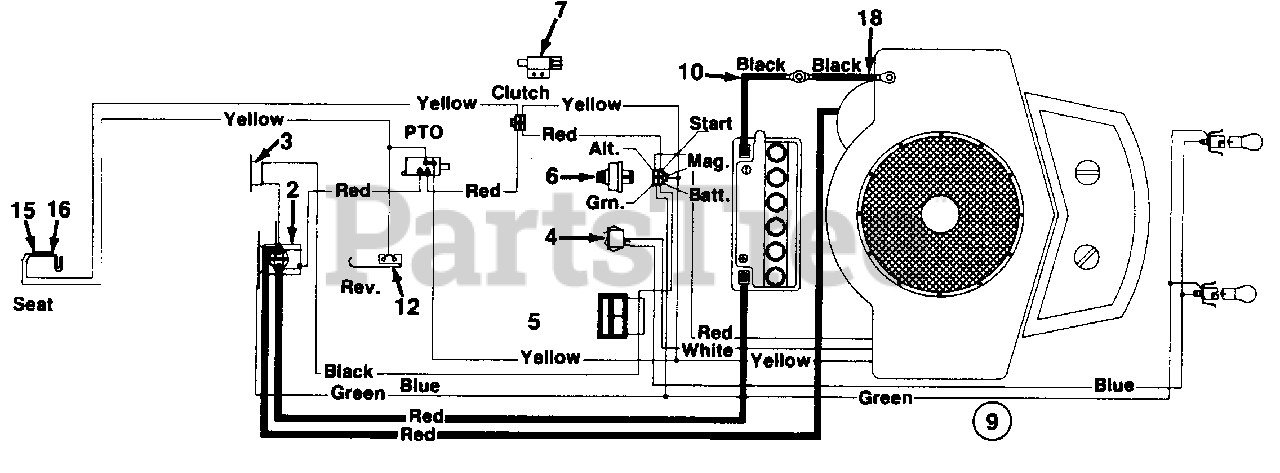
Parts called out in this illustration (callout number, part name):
2	Solenoid
3	Circuit Breaker
4	Light Switch
5	Ammeter
6	Ignition Switch
7	Safety Switch
9	Wire Harness
10	Ground Wire-11.5" Lg.
12	Safety Switch
15	Safety Switch
16	Safety Switch
18	Taillight
